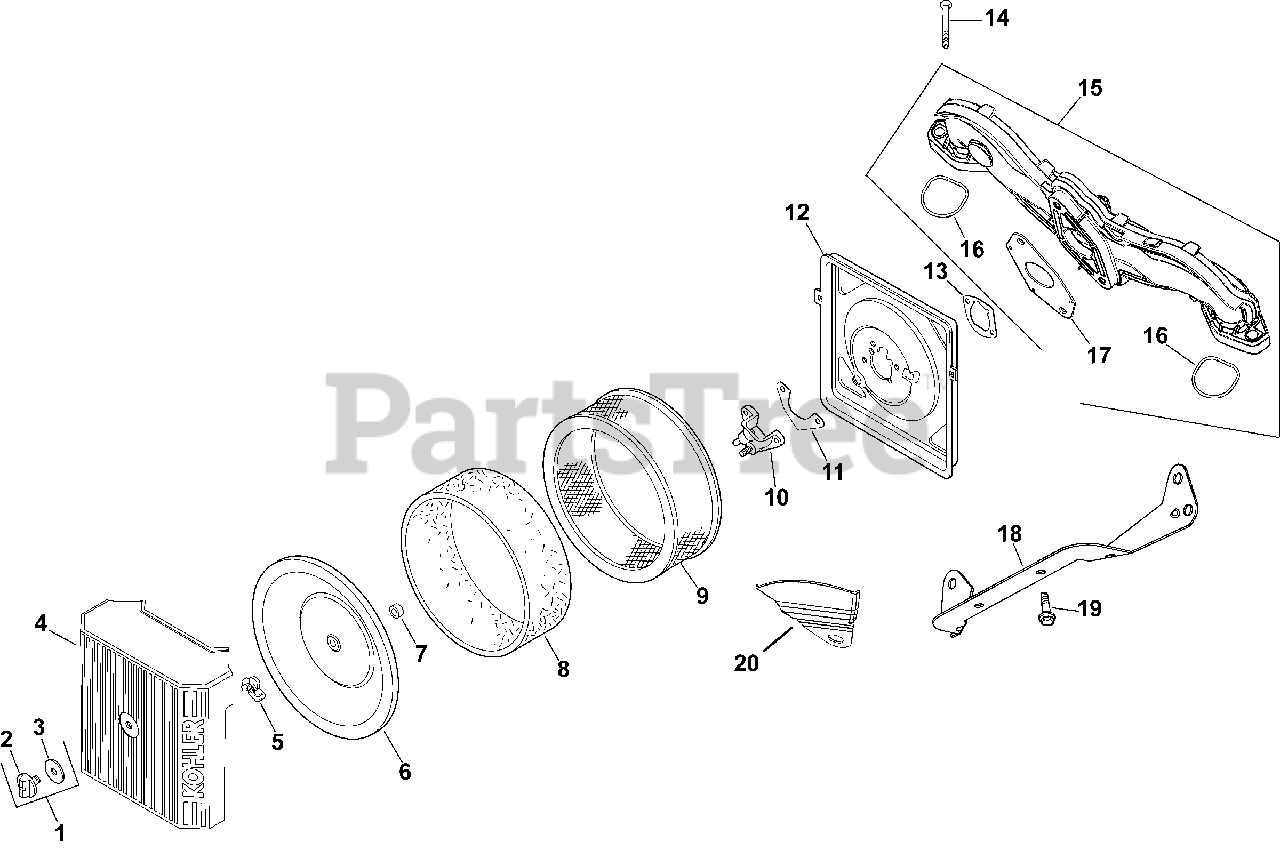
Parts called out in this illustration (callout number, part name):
1	KIT, KNOB W/SEAL
2	KNOB, AIR CLEANER COVER-USE 25 341 04-S
4	COVER, AIR CLEANER
5	NUT, WING
6	COVER, INNER AIR CLEANER
7	SEAL, INNER AIR CLEANER
8	ELEMENT, PRECLEANER (LOW)
9	ELEMENT, AIR CLEANER - Also available Retail Packaged 47 883 03-S1 Air Filter Kit
10	CUP, SPITBACK W/STUD-USE 24 109 26-S
11	GASKET, FUEL SPITBACK CUP
12	BASE, AIR CLEANER-USE 24 094 87-S
13	GASKET, AIR CLEANER BASE
14	SCREW, FLG M6X1.0X40
15	MANIFOLD, INTAKE - PLASTIC-USE 24 164 91
16	O-RING, INTAKE PORT
17	GASKET, CARBURETOR
18	BRACKET, AIR CLEANER BASE
19	SCREW, FLG THD FRM M5X.8X10
20	BAFFLE, SPIT-BACK CUP-USE 24 063 105-S
